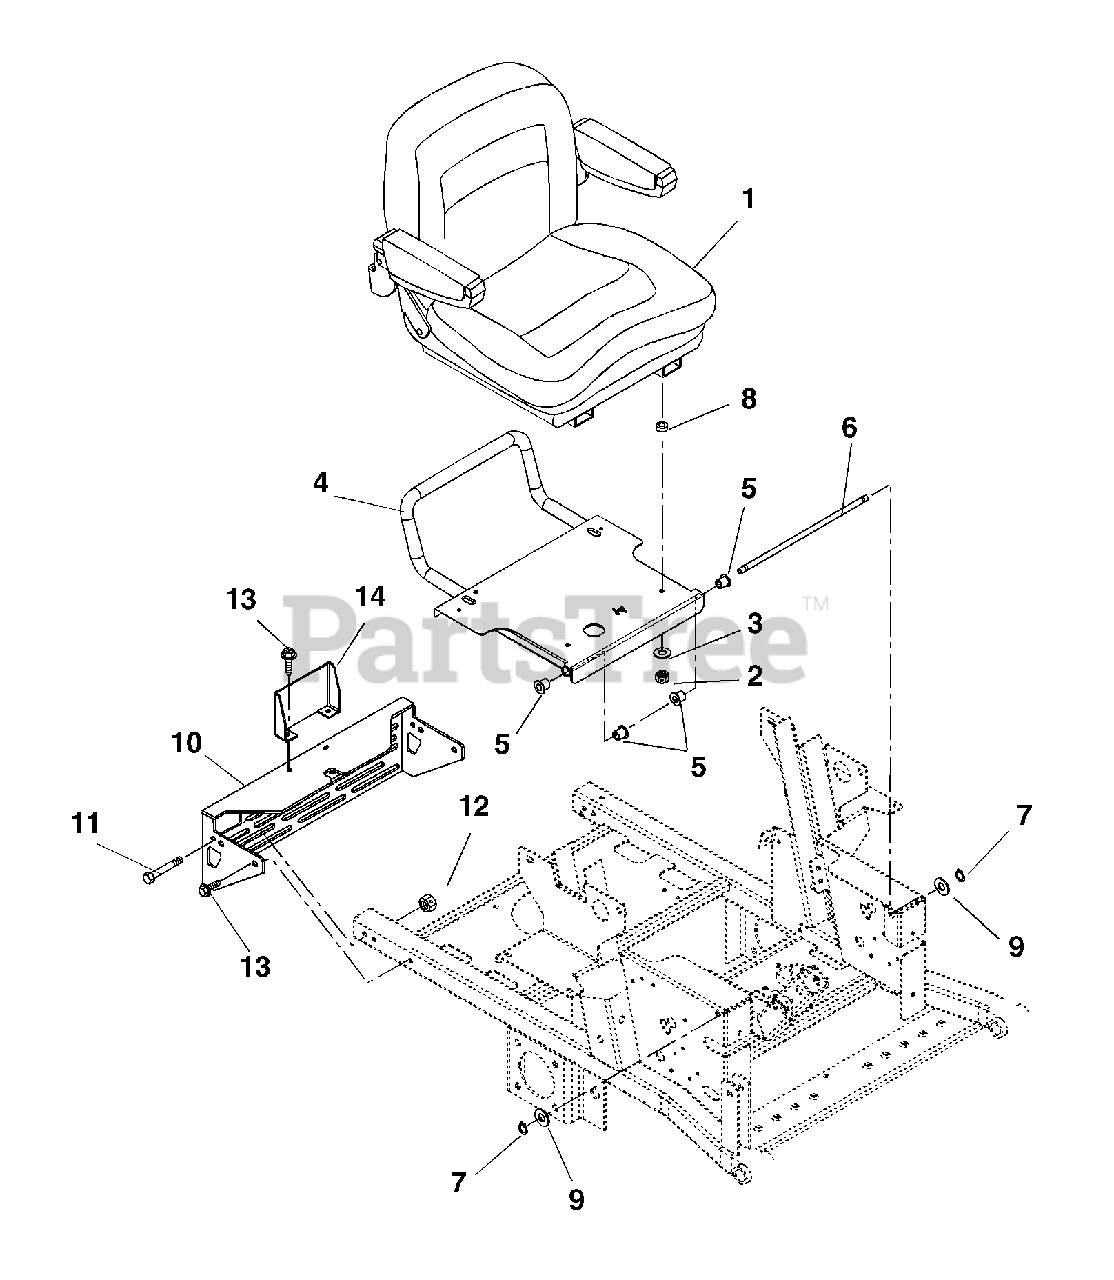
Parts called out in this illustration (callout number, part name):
1	Seat, MILSCO
2	Nut-Locking-Nylon .31-18
3	Washer-Flat-Steel .38 x .875 x .083
4	Weldment- Hood Frame
5	Bushing-Flange .515 x .750 x .745 x 1.00
6	Rod-Seat Frame Pivot
7	Ring-Retaining-External .50 x .05
8	Bushing-Sleeve .377 x .624 x .235
9	Washer-Flat-Steel .531 x 1.06 x .095
10	Bumper-Rear
11	Bolt-Hex .38-16 x 2.75 Grade 5
12	Nut-Locking-Center .38-16
13	Screw-Tapping .38-16 x .75 Hex Washer Head
14	Guard, Engine
